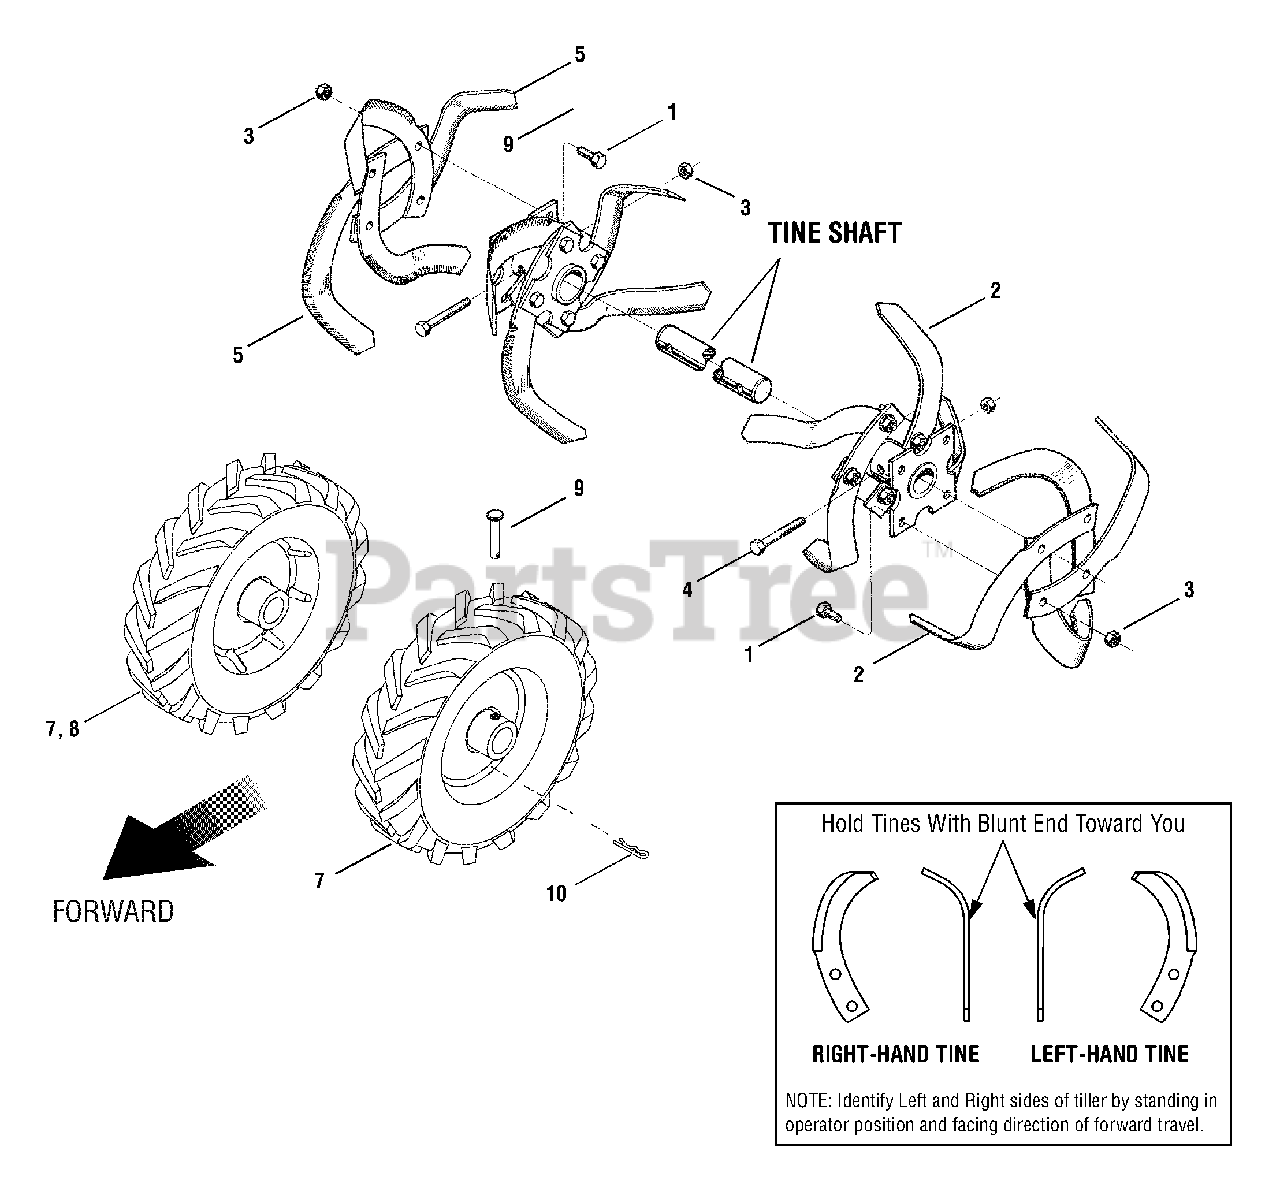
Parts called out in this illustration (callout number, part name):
1	Hex Hd. Screw, 3/8-16 x 1, Grade 5
2	Single Bolo Tine - Left Hand
3	Hex Lock Nut, 3/8-16
4	Hex Hd. Screw, 3/8-16 x 1-3/4
5	Single Bolo Tine - Right Hand
6	Tine Holder
7	Wheel & Tire Ass'y - Left/Right Side
8	Wheel & Tire Ass'y - Right Side Only
9	Clevis Pin, .312" x 1-3/4"
10	Hair Pin Cotter
